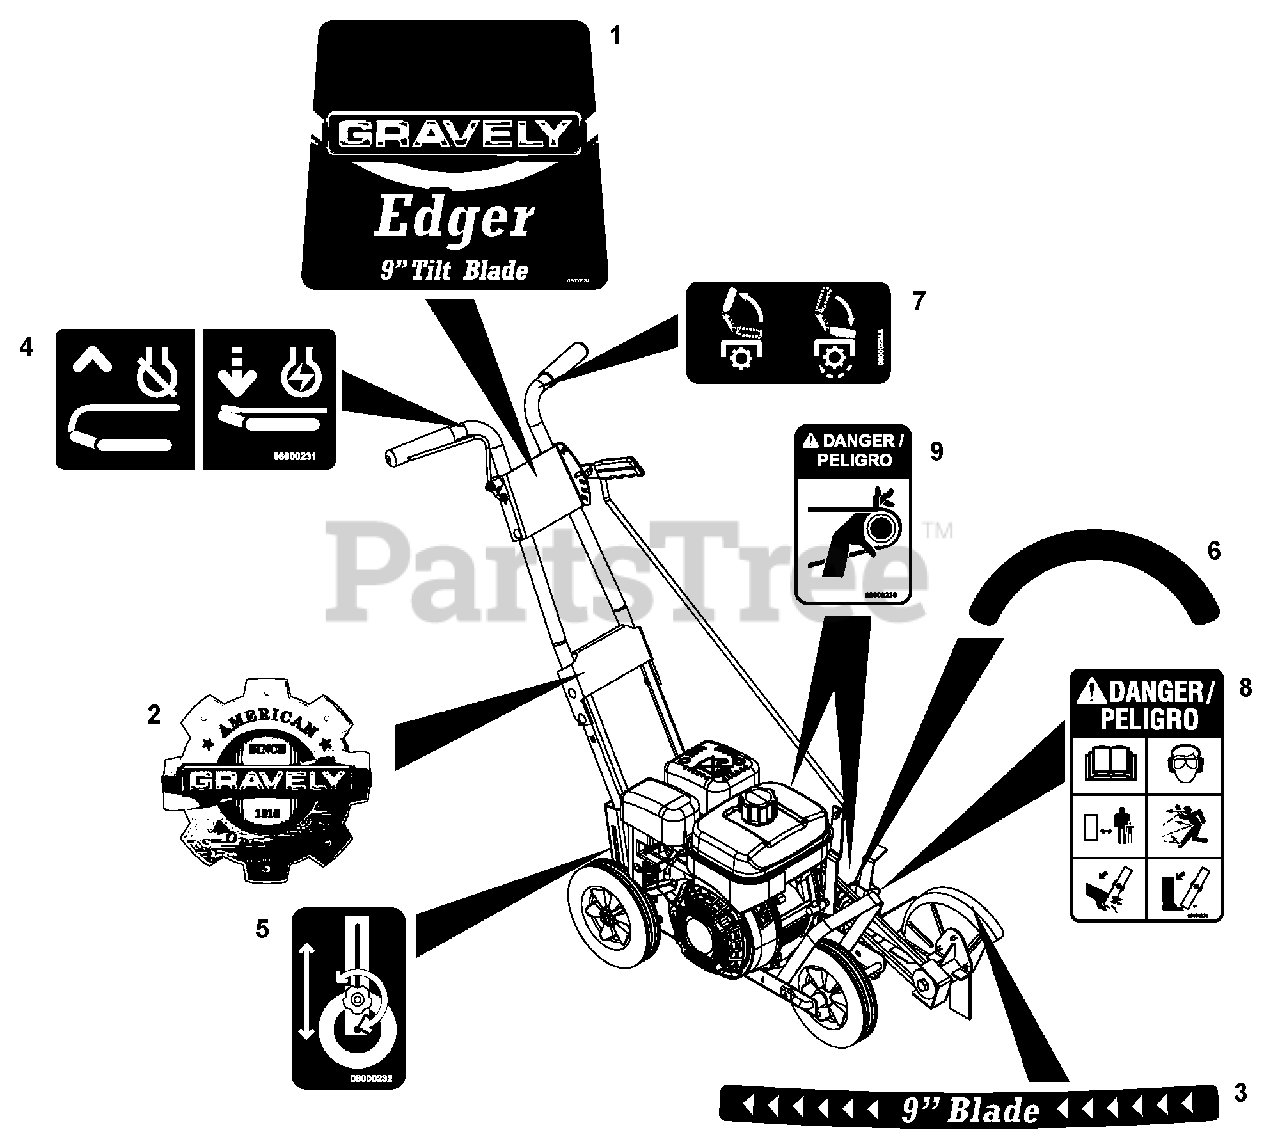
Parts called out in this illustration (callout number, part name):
1	Decal, Edger, Gravely
2	Decal, Gravely Heritage, Small
3	Decal, Edger Blade, Gravely
4	Decal, Edger OPC
5	Decal, Edger Drop Wheel
6	Decal, Edger Blade Tip, Gravely
7	Decal, Edger Depth Control
8	Decal, Edger Warning
9	Decal, Edger Belt Finger
